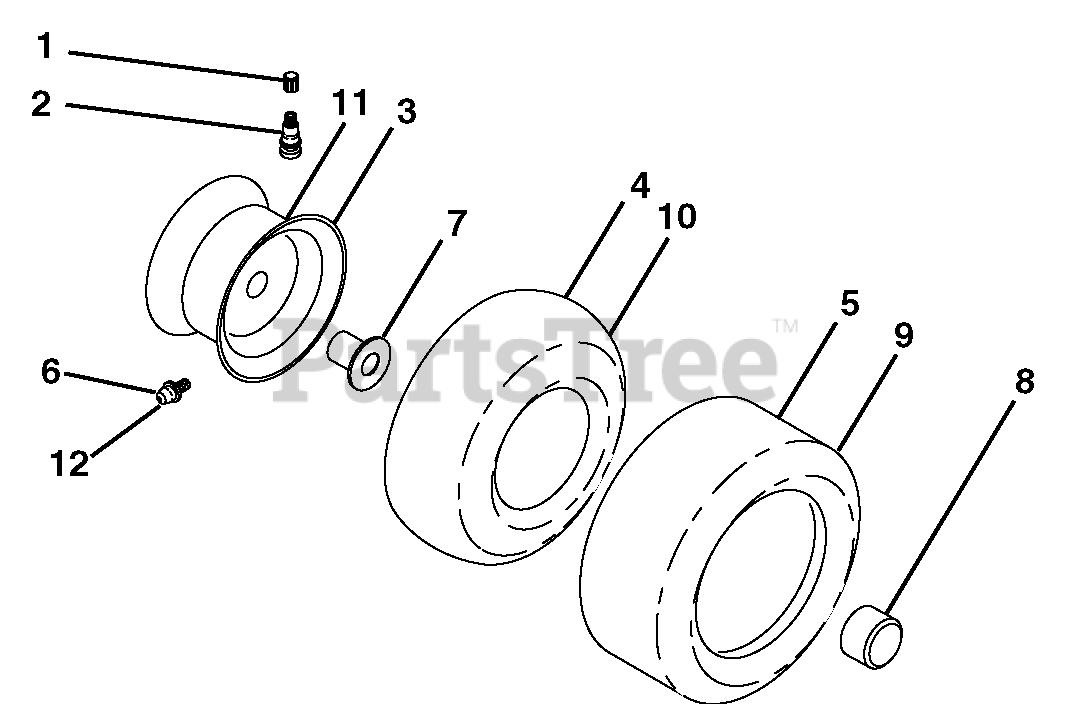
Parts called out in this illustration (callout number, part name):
1	Cap, Valve, Tire
2	Stem, Valve
3	Rim Assembly, Front
4	Tube, Front
5	Tire, Front
6	Fitting, Grease
7	Bearing, Flange
8	Cap, Axle
9	Tire, Rear
10	Tube, Rear
11	Rim Assembly, Rear
12	Fitting, Grease
12	Sealant, Tire (10 oz. Tube)
